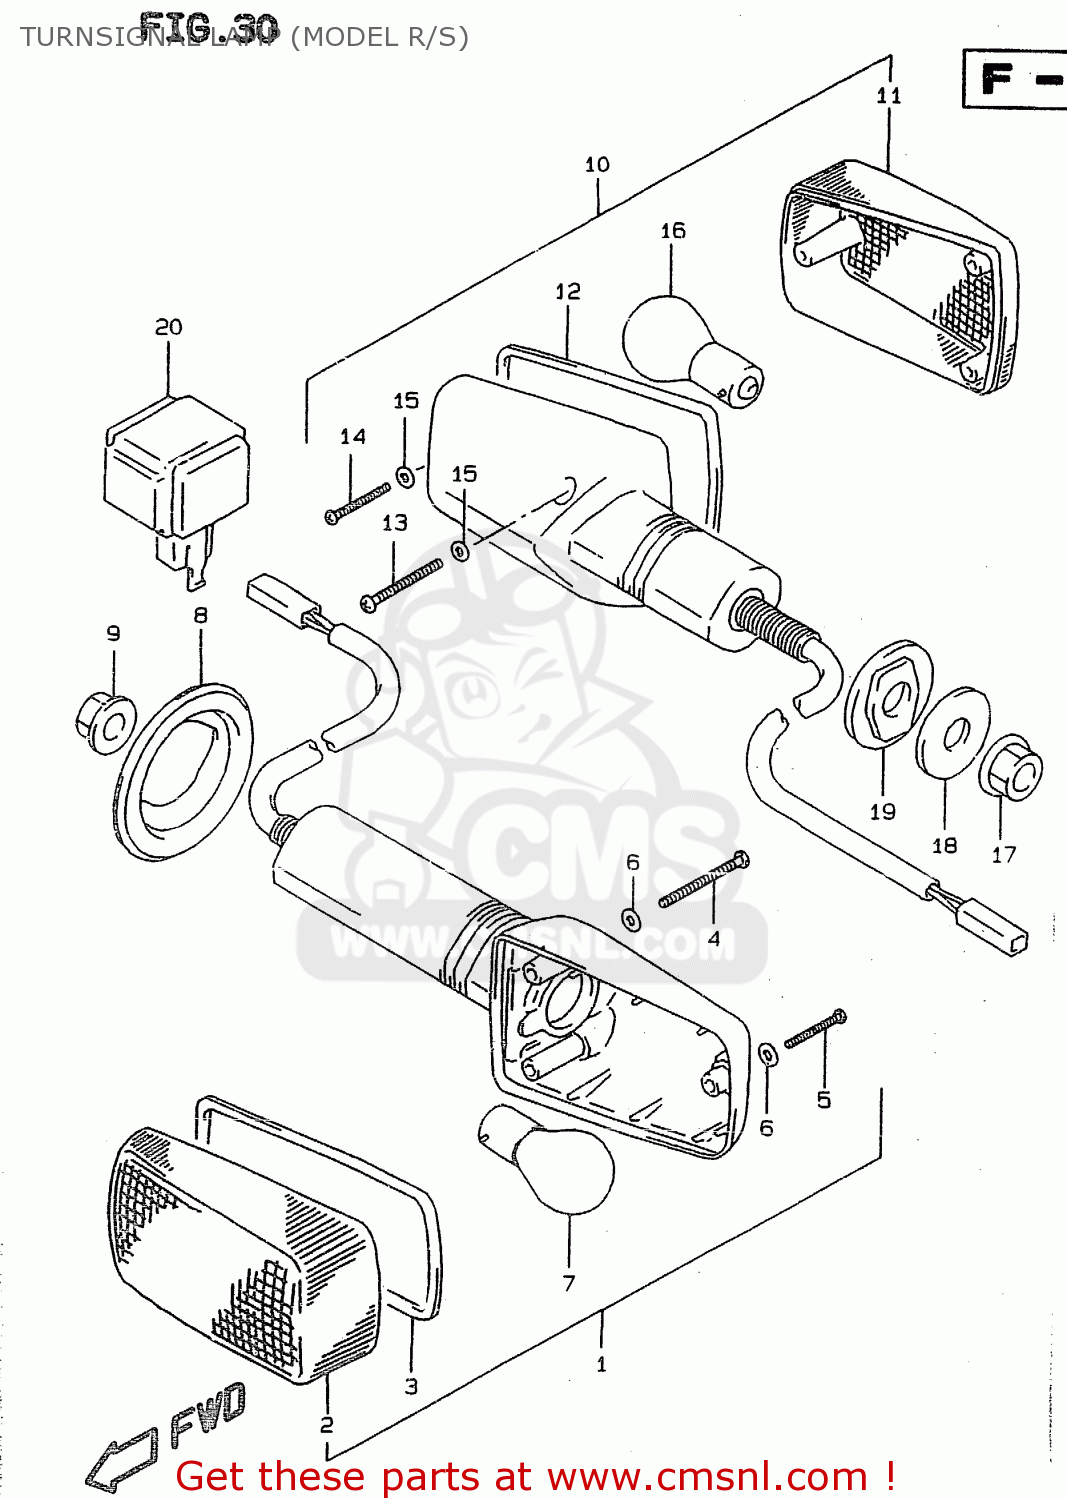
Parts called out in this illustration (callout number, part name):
1	LAMP ASSEMBLY,FRONT TURN SIGNAL
2	LENS
3	GASKET (NAS)
4	SCREW(3X30)
5	SCREW
6	GASKET (NAS)
7	BULB(12V21W)
8	GROMMET
9	NUT
10	LAMP ASSY,RR TURNSIGNAL
11	LENS
12	GASKET (NAS)
13	SCREW(3X30)
14	SCREW
15	GASKET (NAS)
16	BULB(12V21W)
17	NUT
18	WASHER(10.5X30X2.3)
19	SPACER,RR TURNSIGNAL
20	RELAY ASSY,TURNSIGNAL LAMP
